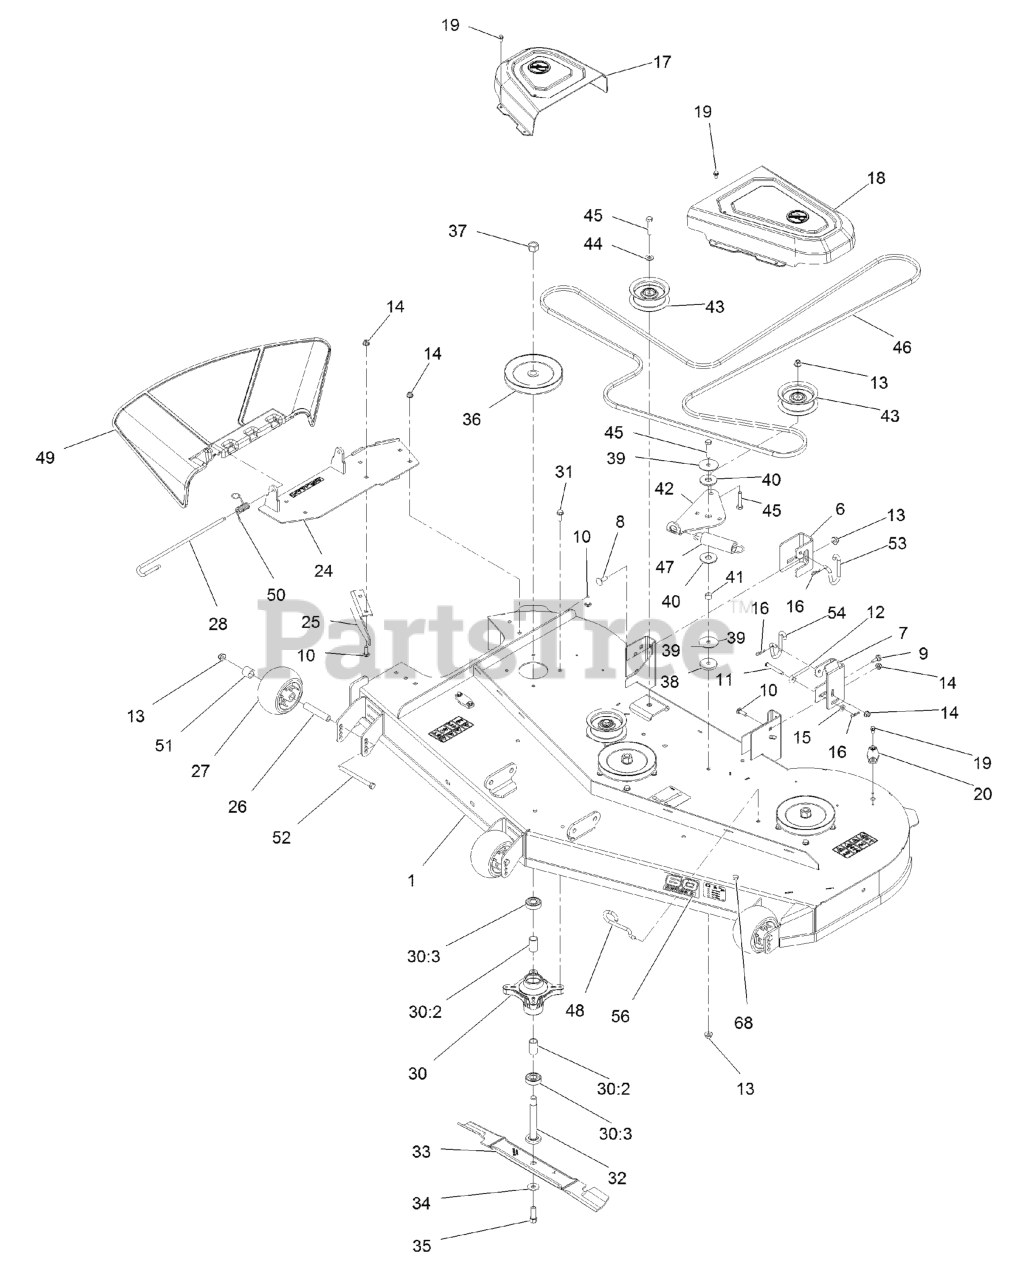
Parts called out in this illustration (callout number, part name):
1	60 INCH DECK AND DECAL ASM
6	BRACKET-HANGER, RH
7	BRACKET-HANGER, LH
8	BOLT-CARR
9	SCREW-SHOULDER,HWH
10	SCREW-CARR
11	PIN-CLEVIS
12	ROD-LEVEL, DECK
13	NUT-HF, NI
14	NUT-HF, NI
15	WASHER-PLAIN
16	PIN-COTTER
17	COVER-BELT, RH
18	COVER-BELT, LH
19	SCREW-HWH
20	COVER-WASHOUT PORT
24	PIVOT-DEFLECTOR
25	BAFFLE-CUTOFF
26	TUBE-SPANNER
27	ROLLER-SCALP, ANTI
28	PIN-CHUTE
30	SPINDLE ASM
30:3	BEARING-BALL
31	SCREW-TAPTITE
32	SHAFT-SPINDLE
33	BLADE-HI FLOW, 20.5 INCH
34	WASHER-BELLEVILLE
35	SCREW-HH
37	NUT-HEX
38	WASHER-PLAIN
40	WASHER-FRICTION, COMPOSIT
42	ARM-IDLER
43	PULLEY-IDLER, FLAT
44	WASHER-FLAT
45	SCREW-HH
46	BELT
47	SPRING-EXTENSION
48	HOOK-RETURN, SPRING
49	DEFLECTOR-DISCHARGE
50	SPRING-TORSION
51	SPACER-AXLE, REAR
52	SCREW-HH
53	LINK-RETENTION, DECK (RH)
54	LINK-RETENTION, DECK (LH)
56	DECAL-SERIES 2 60
68	SCREW-HH
